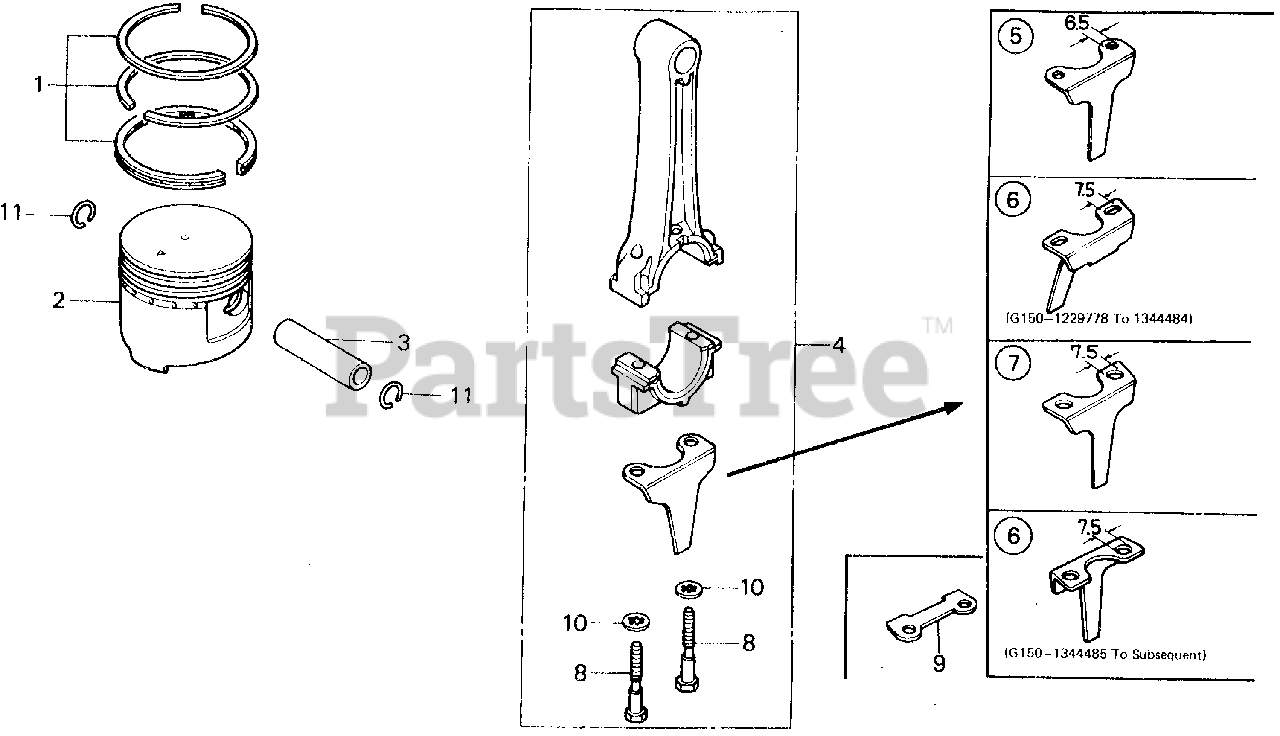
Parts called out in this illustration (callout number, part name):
1	RING SET, PISTON (STD)
1	RING SET, PISTON (OS 0.25)
1	RING SET, PISTON (OS 0.50)
1	RING SET, PISTON (0.75) (OS)
2	PISTON (STD)
2	PISTON (OS 0.25) (OS)
2	PISTON (OS 0.50) (OS)
2	PISTON (0.75) (OS)
3	PIN, PISTON
4	ROD ASSY., CONNECTING
4	ROD ASSY., CONNECTING (US) Use up to Engine SN 1167848.
4	ROD ASSY., CONNECTING (US) Use from Engine SN 1167849 to 1229777.
4	ROD ASSY., CONNECTING Use from Engine SN 1229778.
4	ROD ASSY., CONNECTING (US) Use up to Engine SN 1229777.
5	DIPPER, CONNECTING ROD (NOT AVAILABLE)
6	DIPPER, CONNECTING ROD
7	DIPPER, CONNECTING ROD (NOT AVAILABLE)
8	BOLT, CONNECTING ROD (6MM)
8	BOLT, CONNECTING ROD (6MM) (NOT AVAILABLE)
8	BOLT, CONNECTING ROD (7MM)
9	WASHER B, CONNECTING ROD
10	WASHER, LOCK (6MM) (N/A: SEE ASSEMBLY)
10	WASHER, LOCK (7MM)
11	CLIP, PISTON PIN (15MM)
